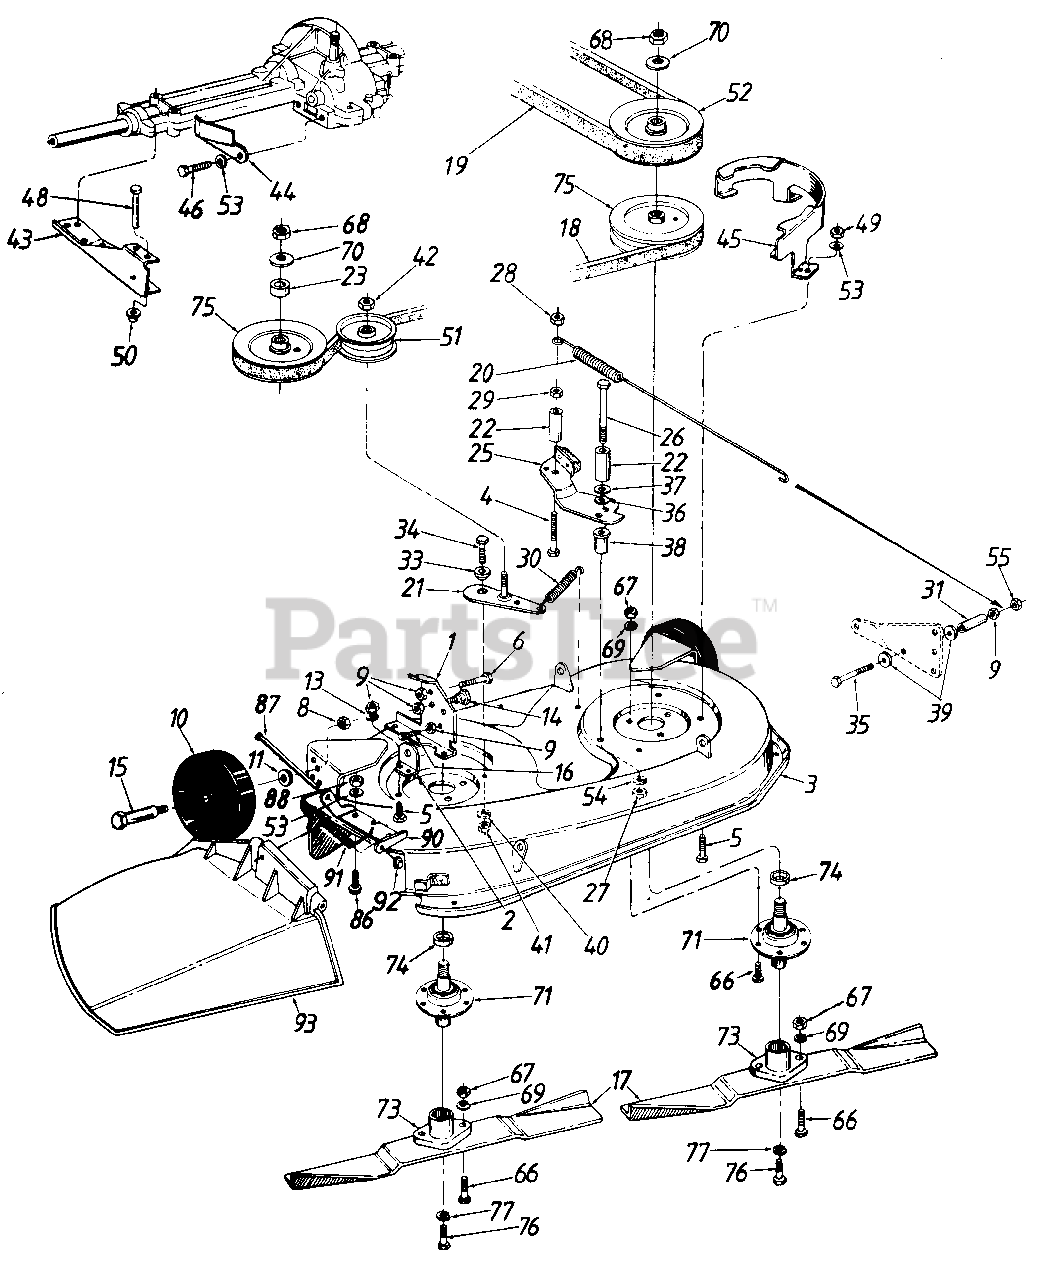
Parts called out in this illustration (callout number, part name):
1	Deck Disengagement Brkt.
2	Rear Deck Brkt.-R.H.
3	32" Deck Ass'y.
4	Hex Bolt 1/4- 28 x 1.75" Lg.
5	Hex Bolt 1/4-20 x .62" Lg.*
6	Hex Wash. Hd. Scr. 1/4-20 x 1.5" Lg.
8	Hex L-Nut 3/8-16 Thd.
9	Hex Nut 1/4-20 Thd.
10	Deck Wheel
11	Bell-Wash. .380" I.D. x .88"
13	L-Wash. 1/4" I.D.
14	Shld. Bolt .500" Dia. x .215"
15	Shld. Bolt .498" Dia. x 1.53"
16	Hex Tap Scr. 1/4-20 x .75" Lg.
17	R.H. High-Lift Blade
18	V-Belt
19	V-Belt
20	Extension Spring 15-5/8" Lg.
21	Idler Brkt. Ass'y.
22	Spacer 5/16" I.D. x 1/2" O.D. x 31/32"
23	Spacer .752" I.D. x 1.25" O.D.
25	Deck Brake Brkt. Ass'y.
26	Hex Bolt 5/16-18 x 3.25" Lg.
27	Hex Nut 5/16-24 Thd.
28	Hex L-Nut 1/4-28 Thd.
29	Hex Nut 1/4-28 Thd.
30	Extension Spring 4.35" Lg.
31	Spacer 1/4" I.D. x 3/8" O.D. x 1-5/16"
33	Shoulder Spacer
34	Hex Bolt 3/8-16 x 1" Lg.
35	Hex Bolt 1/4-20 x 2.5" Lg.
36	Wave Washer
37	Shld. Spacer .27" Lg.
38	Spacer 1.46" Lg.
39	Flat Wash. 1/4"
40	L-Wash. 3/8" I.D.
41	Hex Nut 3/8-16 Thd.
42	Hex L-Nut 3/8-24 Thd.
45	Belt Guard Deck-R.H.
46	Hex Bolt 1/4-20 x .62" Lg.
49	Hex Nut 1/4-20 Thd.
50	Speed Nut 1/4" Rod
51	Flat Idler Pulley
52	5" Dia. Pulley
53	L-Wash. 1/4" I.D.
54	Bell-Wash. 5/16" I.D.
55	Hex L-Nut 1/4-20 Thd.
66	Hex Bolt 5/16-24 x 1" Lg.
67	Hex Nut 5/16-24 Thd.
68	Hex Jam Nut 5/8-18 Thd.
69	L-Wash. 5/16" I.D.
70	Bell-Wash. 5/8" I.D.
71	Blade Spindle Ass'y. Comp.
73	Blade Adapter
74	Spacer
75	5" Dia. Pulley
76	Hex Bolt 3/8-24 x l.on Lg.
77	L-Wash. 3/8" I.D. H.D.
86	Truss.-Mach. Scr. 1/4-20 x .75" Lg.
87	Hinge Pin
88	Hex Nut 1/4-20 Thd.
90	Hinge Mtg. Brkt.
91	Torsion Spring
92	Push Nut
93	Chute Ass'y. Comp.
